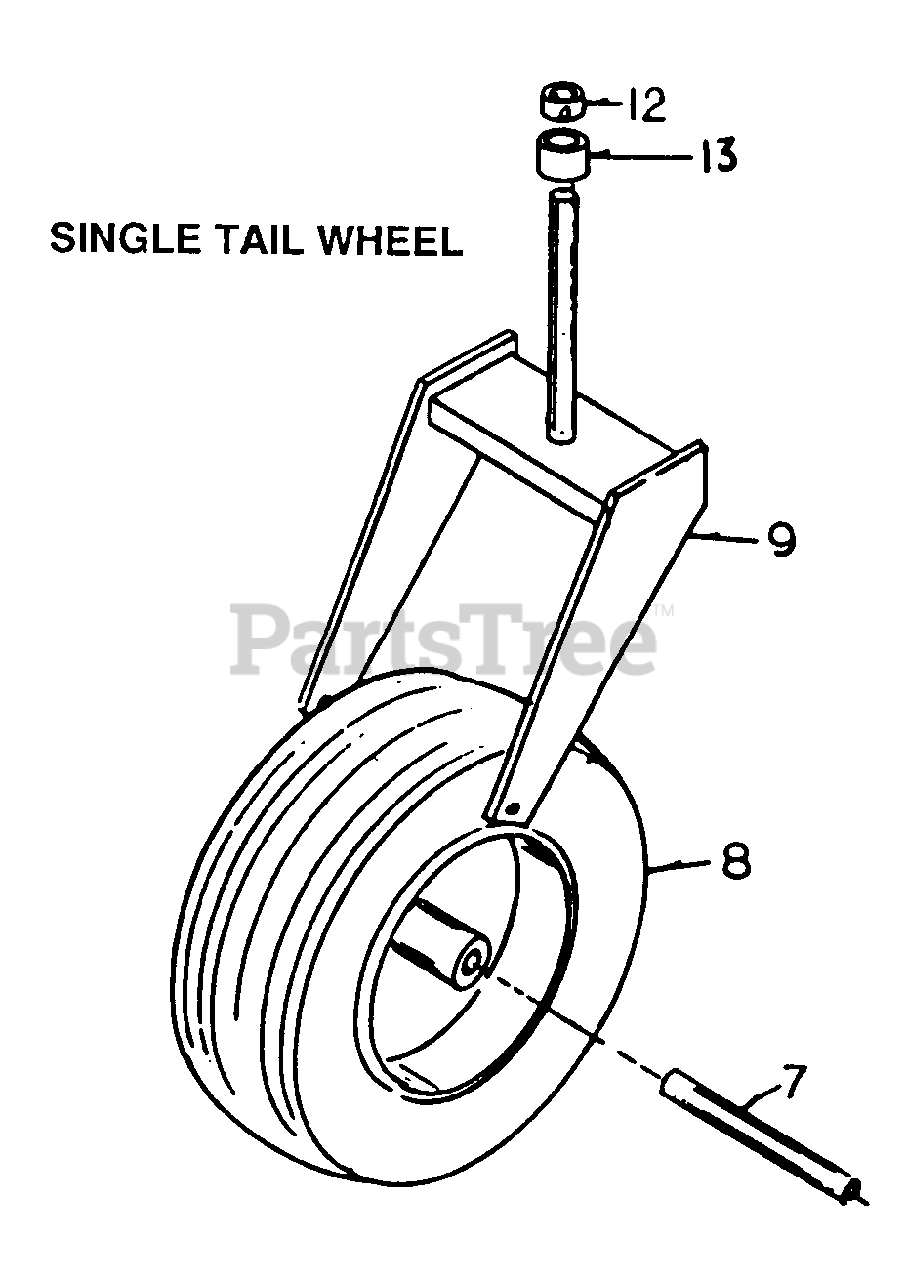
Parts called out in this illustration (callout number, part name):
8	Tail Wheel Assembly
9	Tail Wheel Fork
12	Set Collar, 1"
